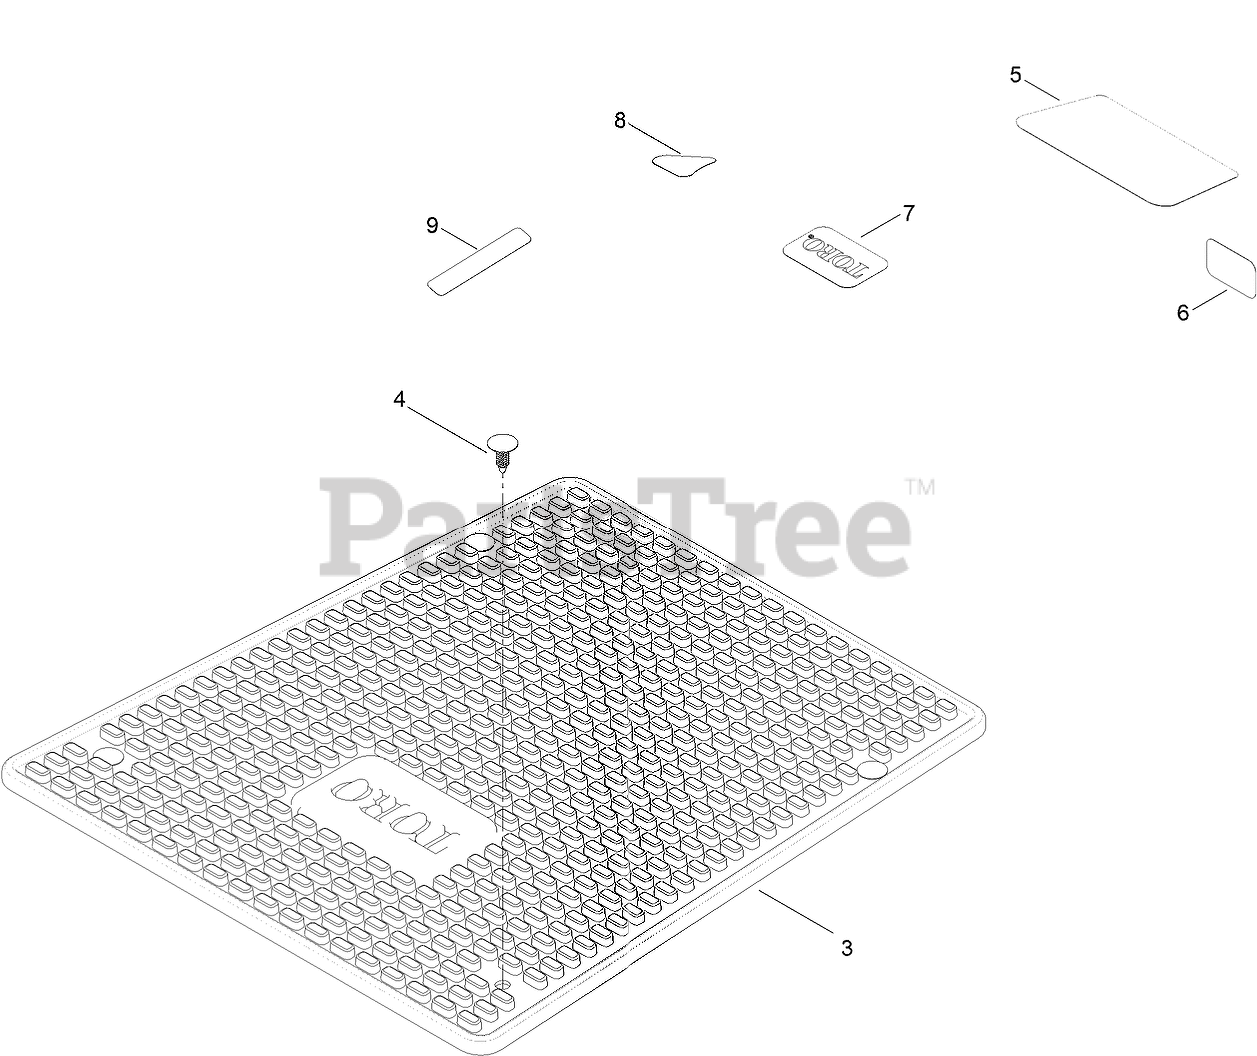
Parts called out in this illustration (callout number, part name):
3	MAT-FLOOR
4	PLUG-PLASTIC
5	DECAL-ENGINE
6	PLACARD-INTAKE
8	DECAL-DRAIN, OIL
9	DECAL-SHUTDOWN
